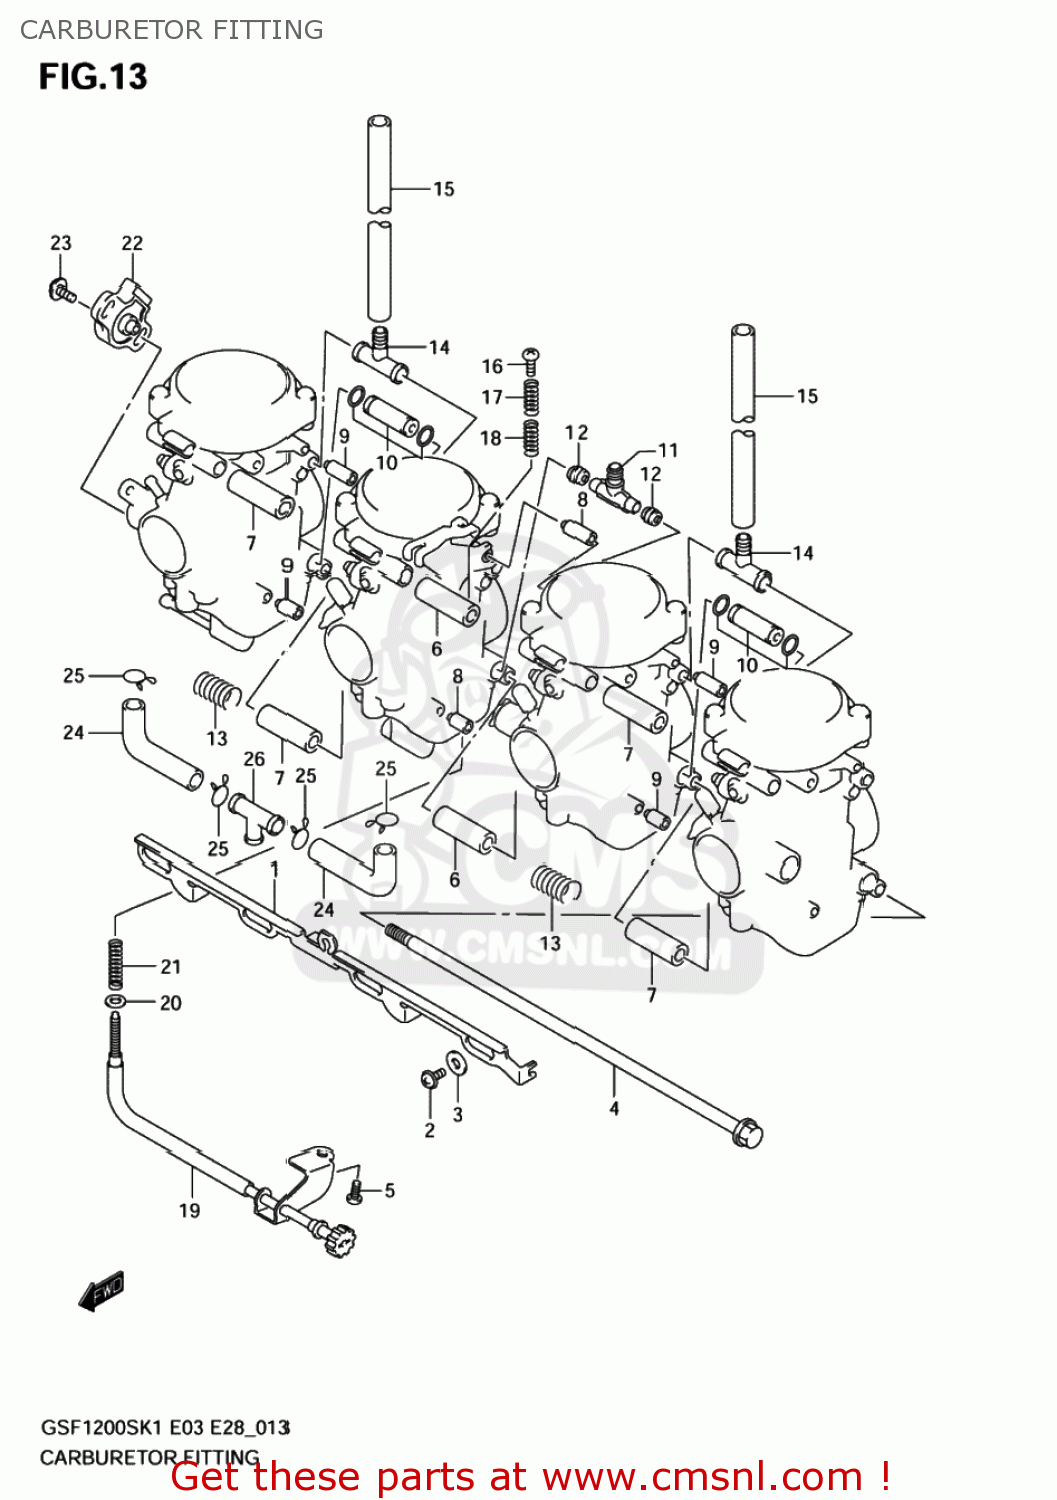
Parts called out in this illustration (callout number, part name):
1	LEVER
2	SCREW
3	PACKING
4	BOLT
5	SCREW
6	PIPE
7	PIPE
8	ROD
9	ROD
10	PIPE
11	NIPPLE
12	SEAL
13	SPRING
14	HOSE
15	HOSE
16	SCREW
17	SPRING
18	SPRING,THROTTLE SCREW
19	SCREW,ADJUST
20	WASHER
21	SPRING
22	SENSOR ASSY,THROTTLE
23	SCREW,SENSOR
24	HOSE
25	CLIP
26	NIPPLE
